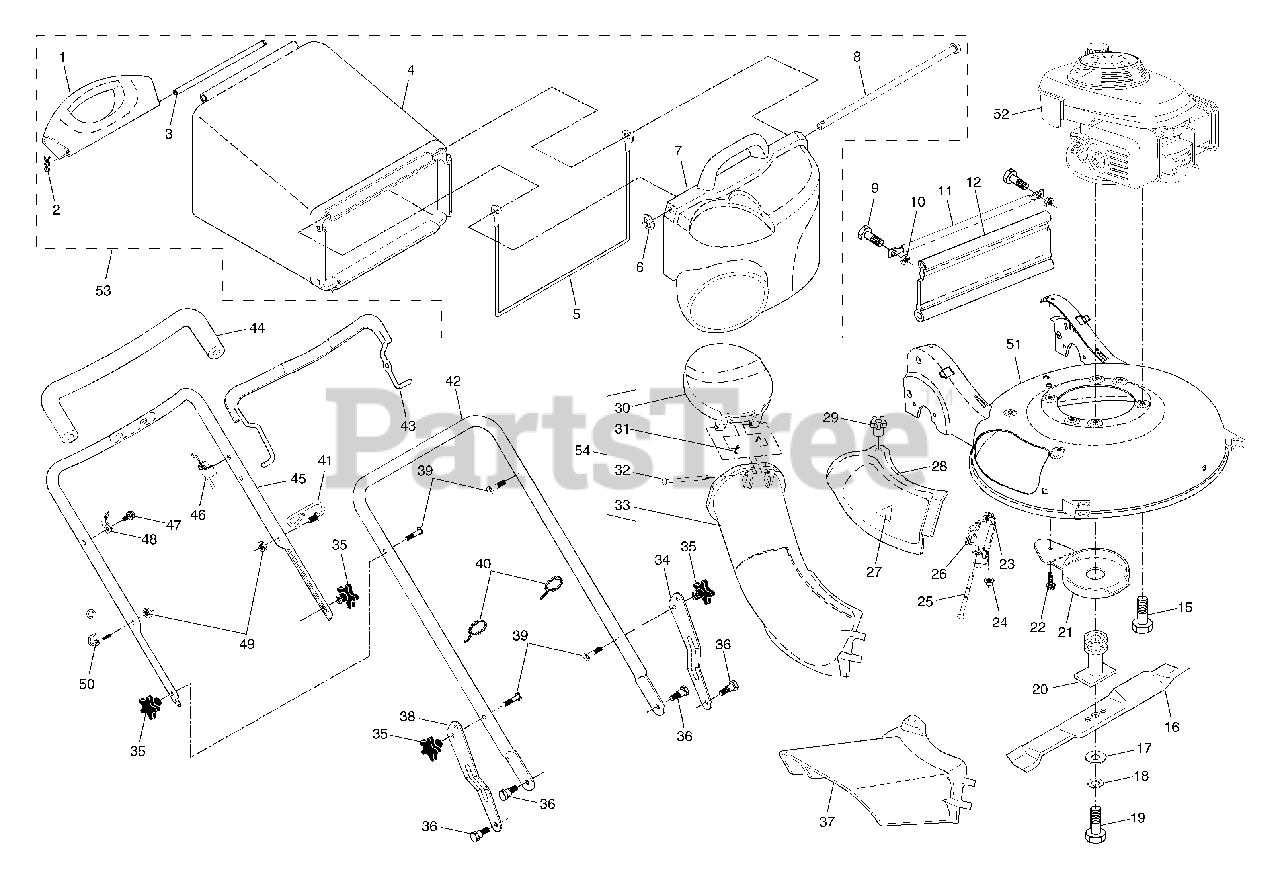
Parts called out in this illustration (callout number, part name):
1	Handle, Grassbag, Rear
2	Hairpin Cotter
3	Rod, Rear Handle, Grassbag
4	Grassbag
5	Frame, Grassbag
7	Door, Grassbag
8	Rod, Pivot
10	Nut, Hex, Nylock 1/4-20
11	Tube, Rear Skirt
12	Skirt, Rear
15	Bolt, Engine Mounting
16	Blade, 21"
17	Washer, Hardened
18	Washer, Lock
19	Screw, Hex Head, Grade 8
20	Adapter, Blade
21	Debris Shield
22	Screw, Hex Head, Serrated
23	Mounting Bracket, Mulcher Door
24	Nut, Hex
25	Rod, Hinge
26	Spring, Mulcher Door
27	Decal, Danger
28	Mulcher Door
30	Door, Discharge Chute
31	Spring, Door, Discharge Chute
32	Rod, Door, Discharge Chute
33	Discharge Chute, Plastic
34	Adjustment Bracket, Lower Handle, LH
35	Knob, Star
36	Bolt, Shoulder
37	Defl ector, Discharge
38	Adjustment Bracket, Lower Handle, RH
39	Bolt, Handle
40	Wire Tie
41	Bracket, Anti-Fold
42	Handle Assembly, Lower
43	Bail, Control
44	Grip, Foam
45	Handle Assembly, Upper
46	Cable, Engine Zone Control
48	Bracket, Upstop
50	Rope Guide
51	Kit, Housing
53	Grass Catcher Assembly, Complete
54	Discharge Chute Assembly, Complete
